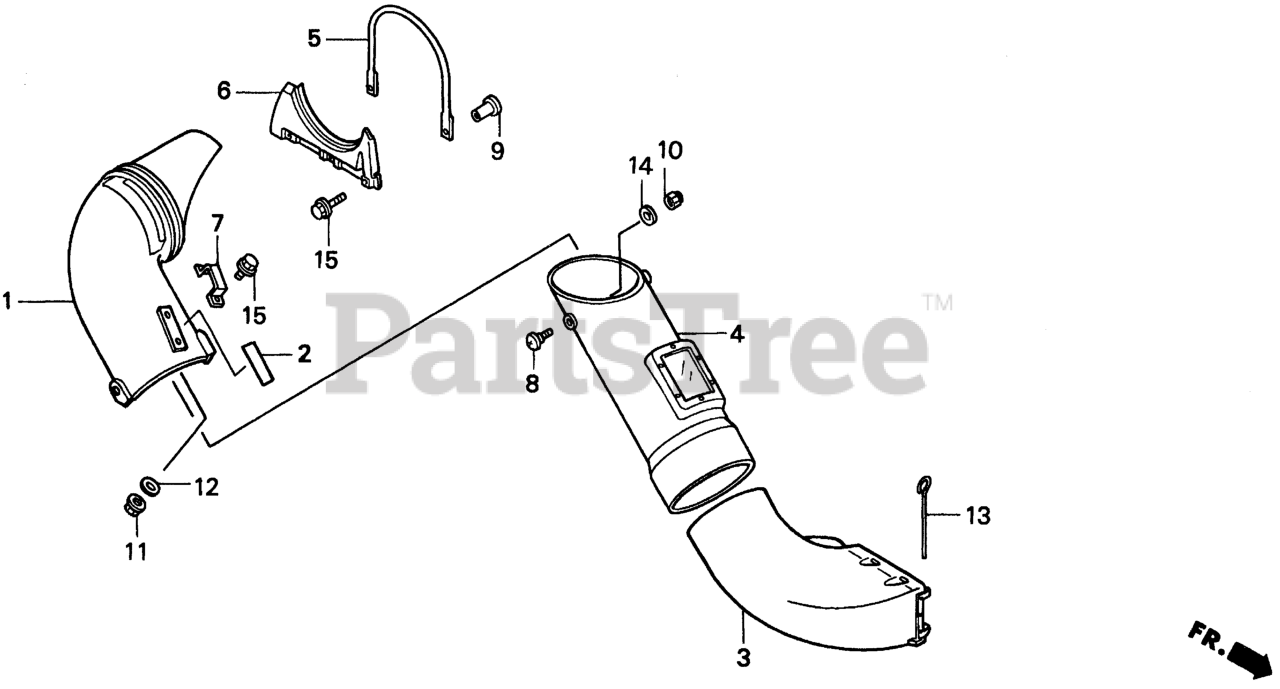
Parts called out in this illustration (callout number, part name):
1	CHUTE (UPPER)
2	LABEL, CHUTE (A)
3	CHUTE (LOWER)
4	CHUTE, MIDDLE
5	SUPPORT, CHUTE
6	SEAL (NOT AVAILABLE)
7	HANDLE, CHUTE (NOT AVAILABLE)
8	BOLT, CHUTE
9	NUT, PIPE (6MM)
10	NUT, NYLON INSERT LOCK (M8-1.25)
11	NUT, SELF-LOCK (6MM)
12	WASHER, PLAIN (0.25 INCH)
13	PIN, CHUTE (LOWER)
14	WASHER, PLAIN (8MM)
15	BOLT, FLANGE (6X16) Use from Engine SN 2056820.
